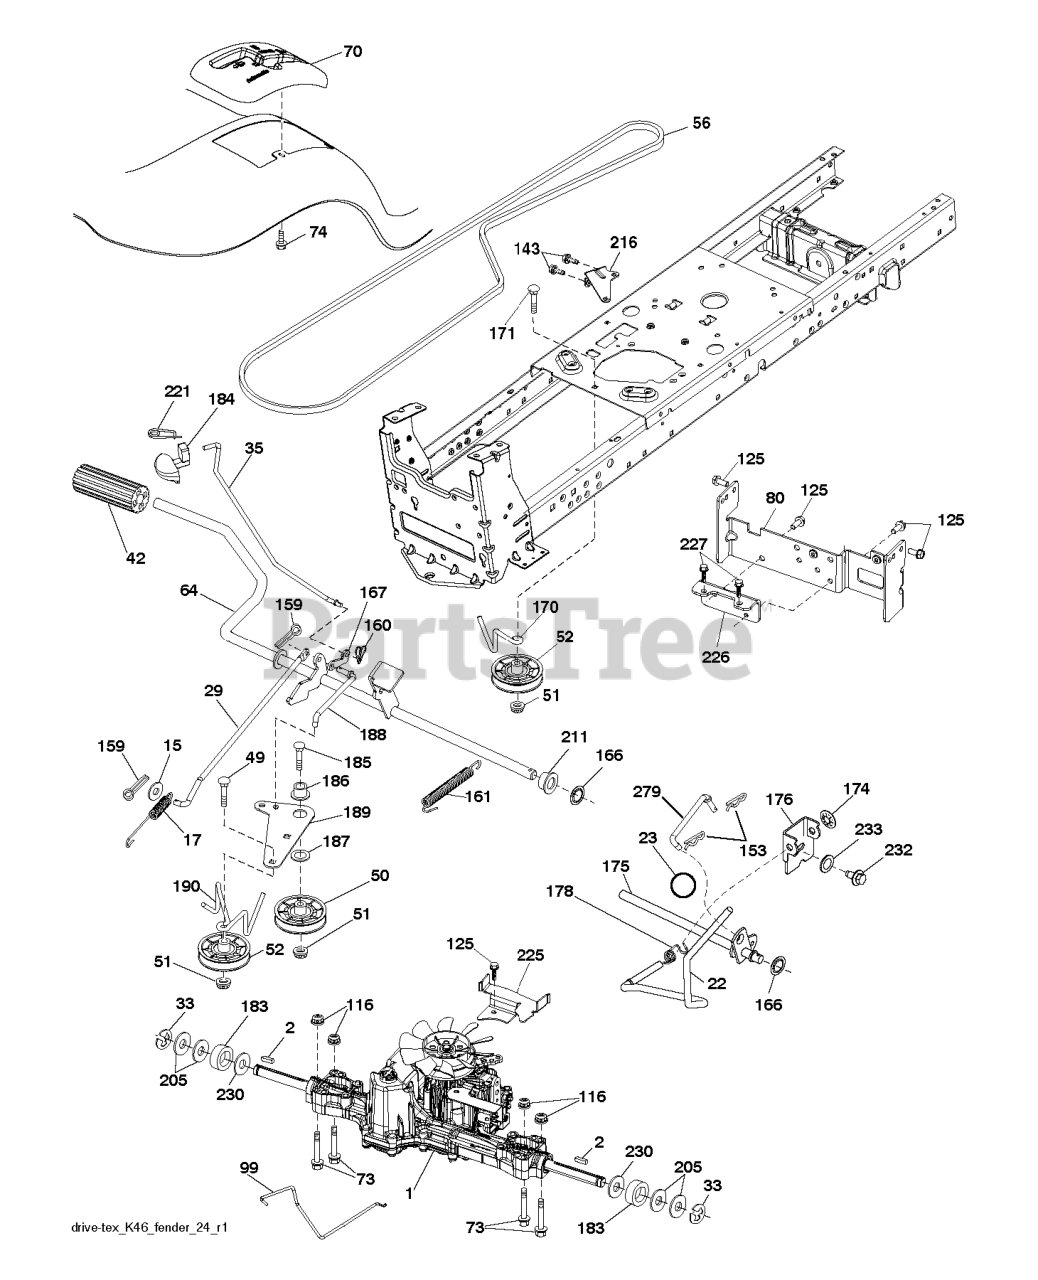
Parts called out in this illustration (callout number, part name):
2	SQUARE KEY
15	WASHER
17	SPRING.BRAKE.K46.GREEN
22	ROD.SHIFT.FENDER.TLT.2006
23	KNOB.DELUXE.(PISTOL.GRIP).BLAC
29	ROD.BRAKE.K46
35	ROD .BRAKE. PARKING. GT. HUSQ.
42	PEDAL COVER T
50	IDLER.FLAT.910.OFFSET
51	NUT LOCK FLG 3/8-16 UNC
52	IDLER.V-GROOVE.910.OFFSET
56	V-BELT.MOWER.92.40.42/K46
64	SHAFT.ASM.PEDAL.BRAKE.
70	CONSOLE.SHIFT.STL.HYD.TEX.GREY
74	SCREW.HI-LO.CONSOLE
80	STRAP TORQUE
99	ROD.SPRING.BYPASS.K46.LT.Z
116	NUT LOCK HEX FLANGE 5/16-18
125	SCREW
143	Screw 5/16-18 x 1/2 Hex, Self Tapping 5/16-18 x 1/2
153	RETAINER M
159	COTTER PIN
160	RETAINER CLIP
161	SPRING, RETURN LT
166	NUT.PUSH.625
167	LATCH.BRAKE.SPRING
170	KEEPER.V-IDLER.CENTER.
174	NUT.PUSH.500.2006
175	SHAFT ASM SHIFT
176	ARM.CLEVIS.ROD.SHIFT
178	SPRING.SHIFT.GT2006
183	SPACER AXLE
184	HANDLE.PARKG.BRK.HUSQ X667
186	SPACER.RETAINER
187	WASHER 12/32X2X10GA
188	RP.LINK.CLUTCH.GROUND.DRIVE
189	BELLCRANK.GROUND.DRIVE.TEX.
190	KEEPER.BELLCRANK.DRIVE
211	BUSHING.SHAFT.BRAKE.HAND
216	BRACKET.PULLEY.IDLER.W/TEX
221	RETAINER.SPRING.CLIP.H
225	KEEPER.BELT.TRANSAXLE.K46
226	BRACKET.MOUNT.TORQUE.K46.TLT
227	SCREW.THDROL.5/16-18X3/4.TTY
230	WASHER.HARDENED
232	BOLT FIN HEX 7/16-14 X 1
233	WASHER SERRATED
279	LINK.SHIFT.T/A.K46.FEND.TX
